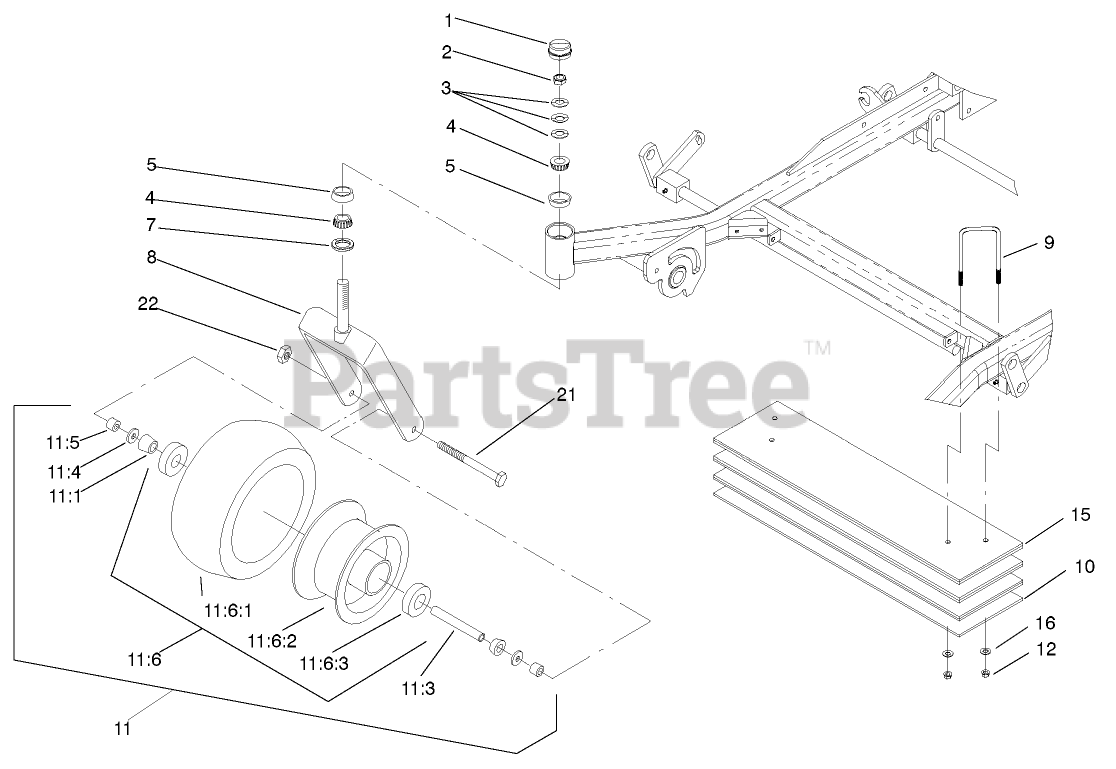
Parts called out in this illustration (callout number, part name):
1	CAP-GREASE
2	NUT-LOCK, NI
3	WASHER-BELLVILLE
4	BEARING-CONE, TAPERED
5	BEARING-CUP, TAPERED
7	SEAL-GREASE
8	CASTER
9	U-BOLT
10	BAR-WEIGHT
11	CASTER WHEEL ASM
11:1	BEARING-CONE, TAPER
11:3	SPACER-CASTER, FRONT
11:4	SEAL-BEARING
11:5	SPACER-BEARING
11:6	Wheel AND Tire ASM
11:6:3	BEARING-CUP
12	NUT-LOCK, NI
15	WEIGHT BAR ASM
16	WASHER-FLAT
21	SCREW-HH
22	NUT-LOCK, NI
